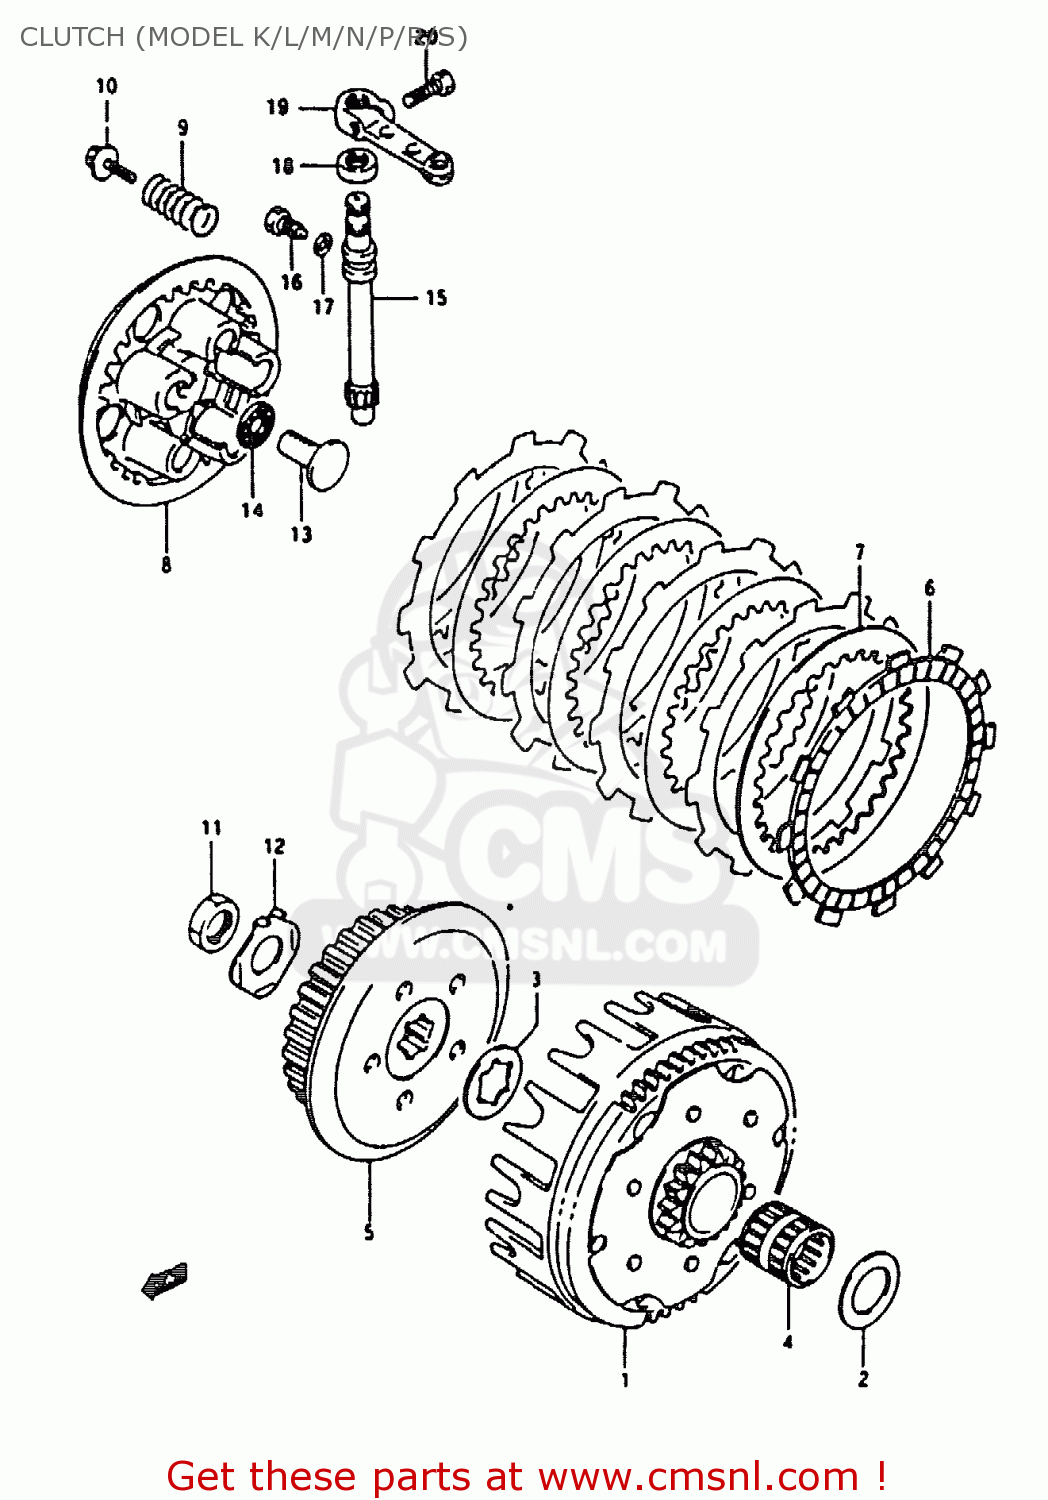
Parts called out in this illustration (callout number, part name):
1	GEAR ASSY,PRI DRIVEN(NT:62/16)
2	WASHER,THRUST
3	WASHER,LOCK
4	BEARING(20X25X26)
5	HUB COMP,CLUTCH SLEEVE
6	PLATE,CLUTCH DRIVE(T:3.0) (NAS)
7	PLATE,CLUTCH DRIVEN(T:2.0) (NAS)
8	DISC,CLUTCH PRESSURE
9	SPRING
10	BOLT 5X16
11	NUT
12	WASHER
13	RACK,CLUTCH RELEASE
14	BEARING(10X22X2.8)
15	PINION,CLUTCH RELEASE
16	BOLT
17	GASKET(6.2X11X1).2 (NAS)
18	SEAL,OIL(10X17X5)
19	ARM,CLUTCH RELEASE
20	BOLT
